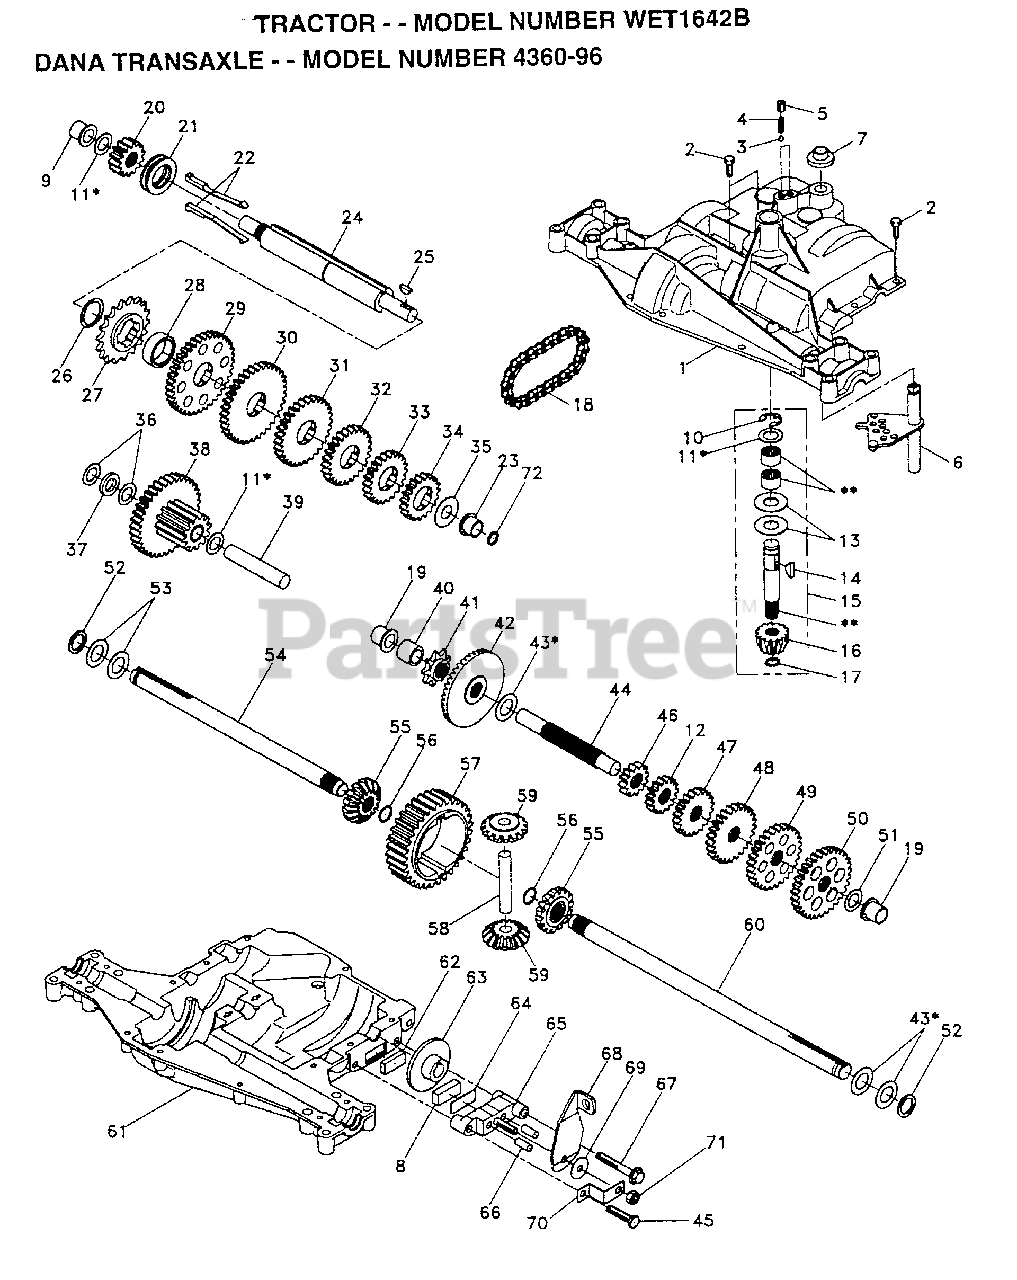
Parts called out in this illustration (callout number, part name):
1	HARNESS.IGNITION
4	"SPRING, DETENT LT"
5	"SCREW, SET LT"
6	KIT SHIFTER ASM
7	SHIFTER BOOT
8	PUCK T
10	RETAINING RING LT
11	ASM KIT SHIM 4689
12	PLUG.PLASTIC
13	WASHER T
14	KEY WOODRUFF-DANA
17	"RING,RETAINING LT"
18	"CHAIN,24 PTCH LT"
19	BEARING.FLNG.5510
20	GEAR SPUR 14 TTH
21	CLUTCH.COL.5467
22	KIT.ASM.CLUTCH KY
23	BEARING.FLNG.5511
24	SHAFT INTERM DANA
25	WOODRUFF KEY
26	"RING,RETAINING LT"
27	SPROCKET 18T T
28	SPACER YT
29	GEAR SPUR 37 TTH
30	GEAR SPUR 35 TTH
31	GEAR SPUR 30T
32	GEAR 25T LT
33	GEAR SPUR 22 TT
34	SPUR GEAR 19T
35	"WASHER, PLAIN LT"
36	WASHER 025
37	SPACER
38	ASSM GEAR COMB
39	SHAFT IDLER
40	SPACER T
41	SPROCKET 9T LT
43	ASM KIT SHIM
44	SHAFT T
45	"SCREW, TAPPING LT"
46	GEAR SPUR 12 TTH
48	"GEAR, SPUR 25T LT"
49	GEAR 28T T
50	"GEAR, SPUR 31T LT"
51	WASHER 060
52	NEOPRENE WASHER
53	WASHER 031
55	GEAR 15T T
56	"RING,RETAINING LT"
58	SHAFT T
59	GEAR 1ST T
61	HOUSING LOWER TNS
62	PUCK T
63	BRAKE DISC. T
64	SPACER LT
66	PIN T
69	WASHER LT
71	NUT.LOCK.5/16-24
72	SEAL.OIL.DAN.5508
